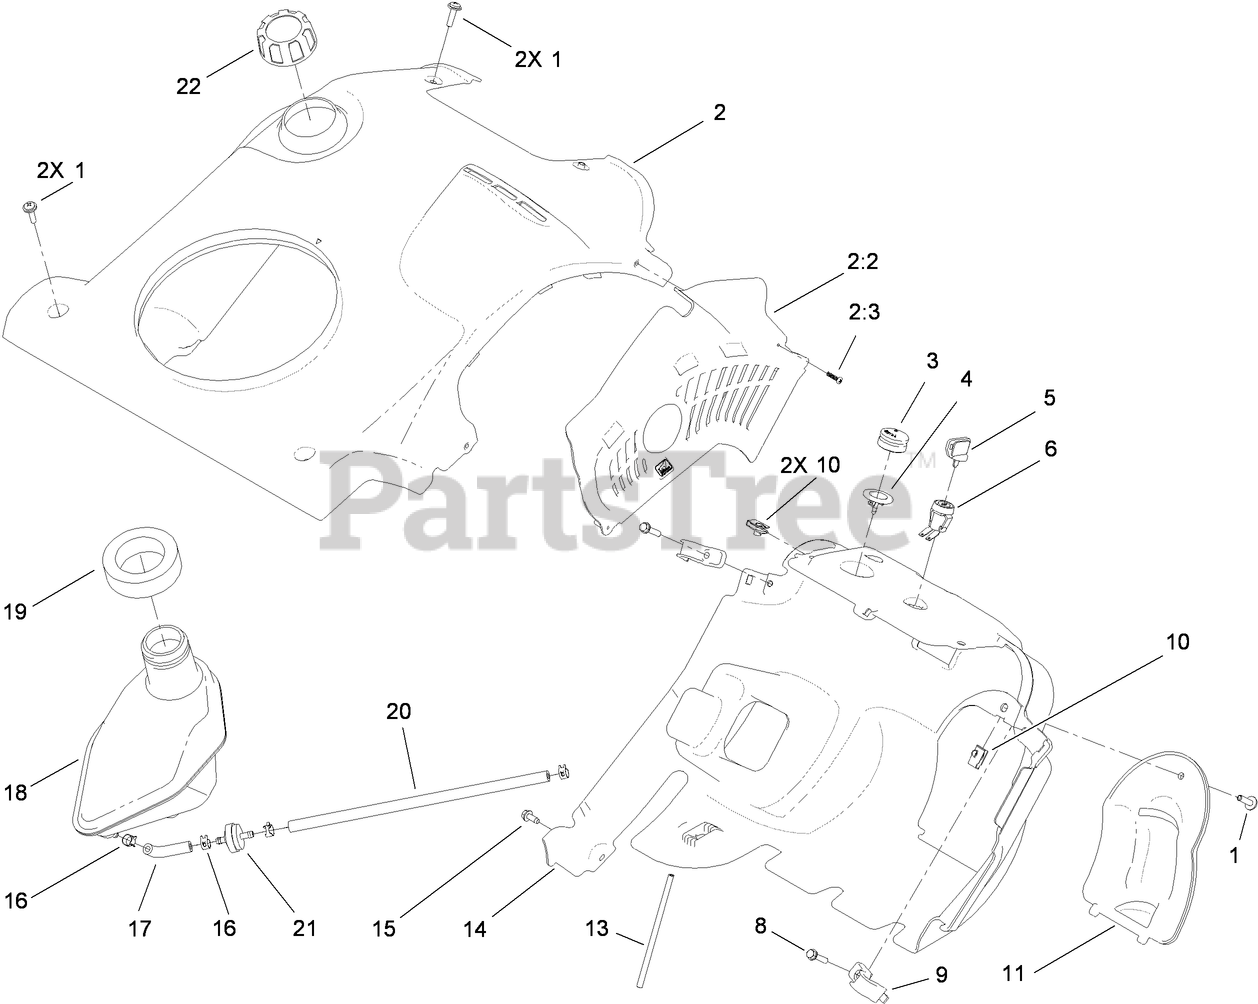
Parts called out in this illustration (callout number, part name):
1	SCREW-PPH
2	SHROUD ASM
2:2	BAFFLE-HEAT
2:3	SCREW-PPH
3	BULB-PRIMER
4	BODY-PRIMER
5	KEY-IGNITION
6	SWITCH
8	SCREW-PLASTITE
9	CLIP-SHROUD
11	PANEL-ACCESS, CARBURETOR
13	HOSE-PRIMER
14	SHROUD-LOWER
15	SCREW-HWH
16	CLAMP-HOSE
17	HOSE-FUEL
19	SEAL-TANK
20	HOSE-FUEL
21	FILTER-FUEL
22	GAS CAP ASM
